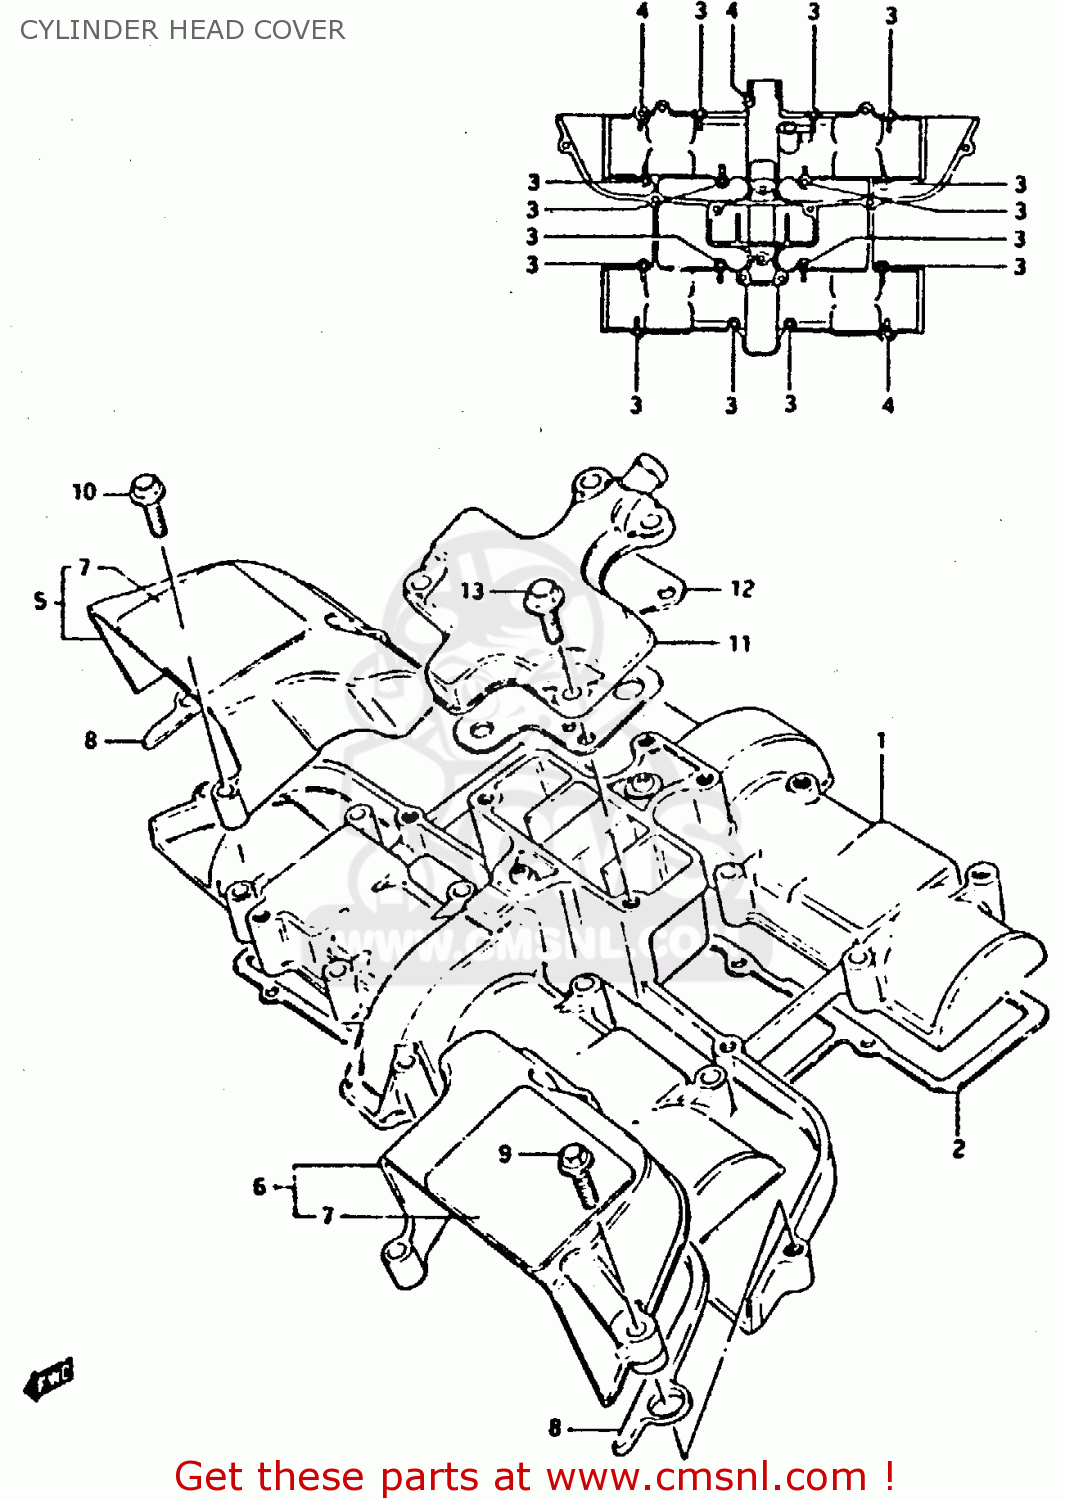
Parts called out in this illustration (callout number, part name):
1	COVER,CYLINDER HEAD
2	GASKET,CYLINDER HEAD COVER (MCA)
3	BOLT
4	BOLT,UNDER
5	COVER,AIR GUIDE,RIGHT
6	CYLINDER
7	CAP,CYLINDER COVER NO
8	CUSHION
9	BOLT
10	BOLT 6X35
11	COVER,BREATHER
12	GASKET (MCA)
13	BOLT,REAR
